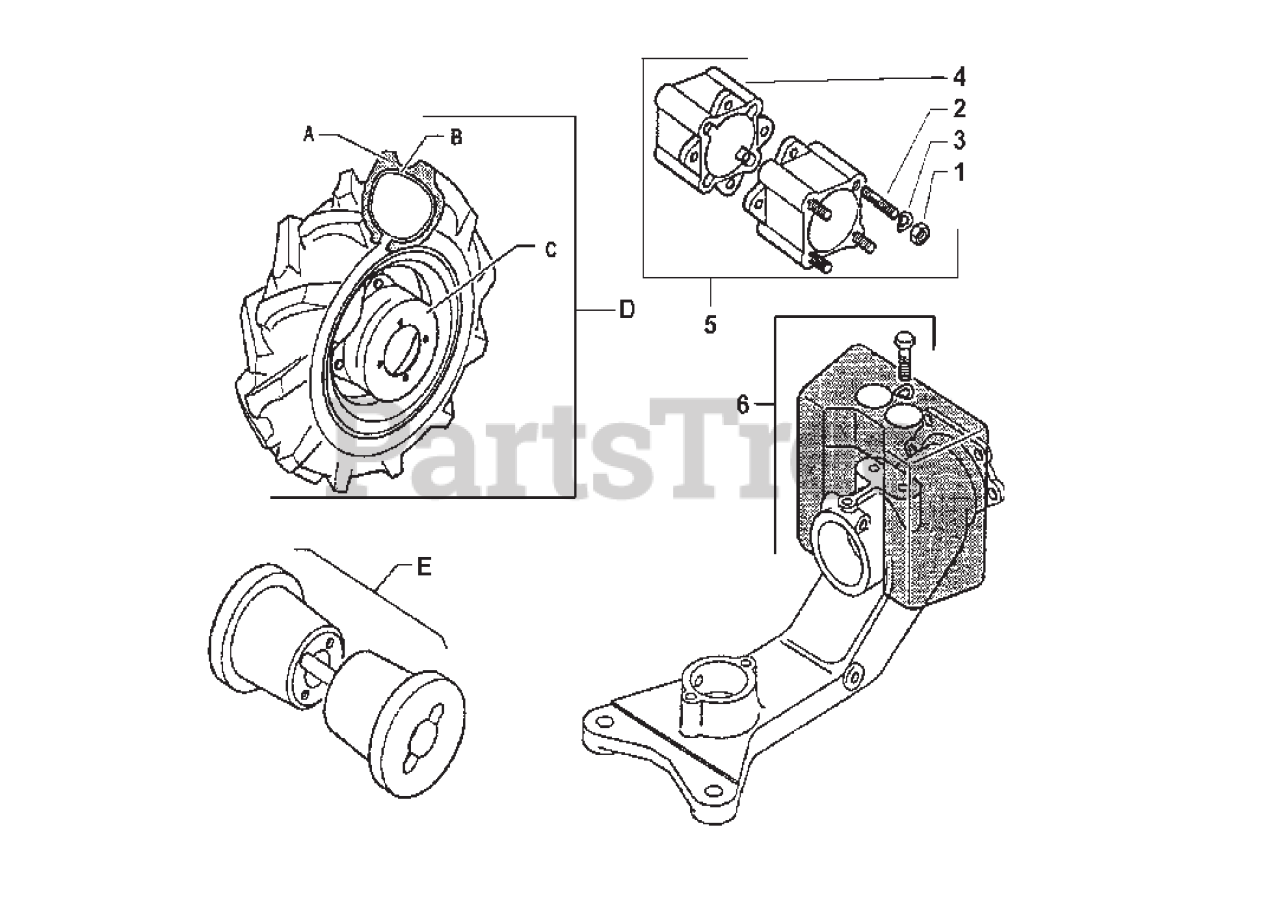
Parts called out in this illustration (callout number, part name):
1	NUT, M10
2	STUD, M10X40X24X12
3	WASHER, M10.5
4	USE ITEM# 922.4385
5	PAIR WHEEL EXTENSIONS COMPLETE
A	TIRE 3.50 - 8"
A	TIRE 4.00 - 8"
A	TIRE 4.00 - 10"
A	TIRE 5.00 - 10"
A	TIRE 5.00 - 12"
A	TIRE 6.50 - 12"
B	TUBE 3.50 - 8"
B	TUBE 4.00 - 8"
B	TUBE 4.00 - 10"
B	TUBE 5.00 - 10"
B	TUBE 5.00 - 12"
B	TUBE 6.50 - 12"
C	RIM 3.50 - 8" & 4.00 - 8"
C	RIM 4.00 - 10" & 5.00 - 10"
C	RIM 5.00 - 12" & 6.50 - 12"
D	PAIR WHEELS COMPLETE 15 X 3.50 - 8"
D	PAIR WHEELS COMPLETE 16 X 4.00 - 8"
D	PAIR WHEELS COMPLETE 18 X 4.00 - 10"
D	PAIR WHEELS COMPLETE 19 X 5.00 - 10"
D	PAIR WHEELS COMPLETE 22 X 6.50 - 12"
D	PAIR WHEELS COMPLETE 22 X 5.00 - 12"
